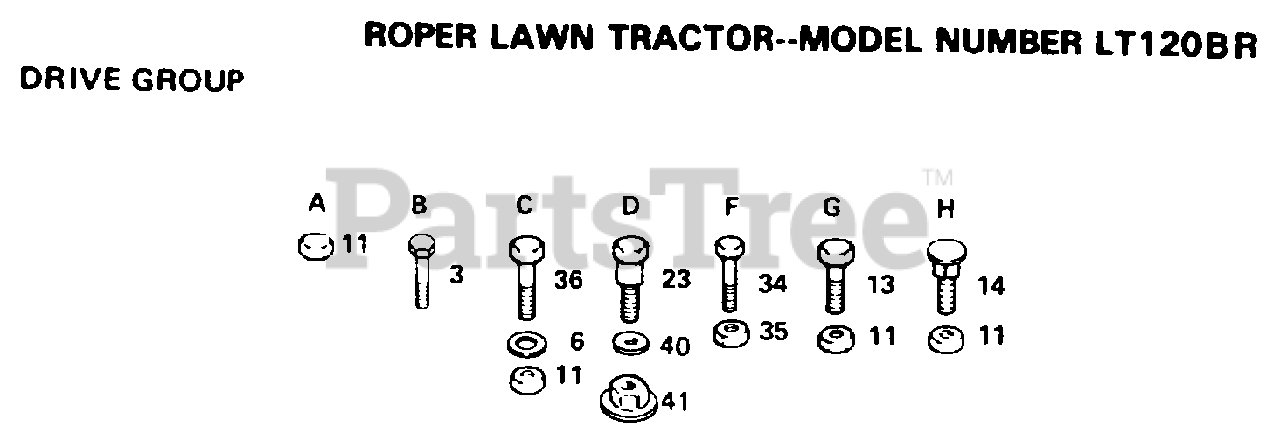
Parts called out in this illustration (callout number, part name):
3	SCREW
6	WASHER
14	BOLT
23	"BOLT, SHOULDER LT"
34	BOLT
36	BOLT
40	WASHER T
41	NUT SPECIAL T
